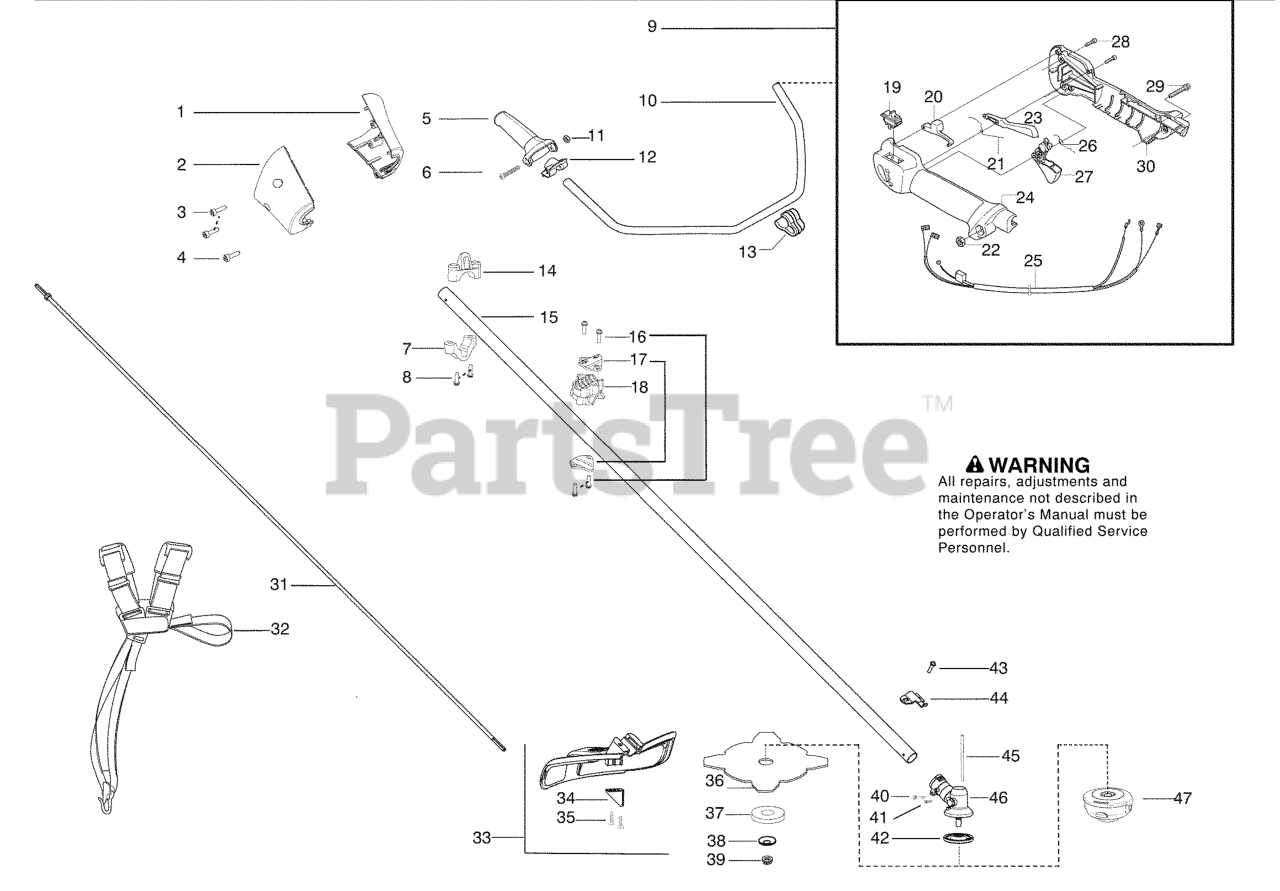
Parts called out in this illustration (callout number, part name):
1	NOSE CONE BH LEFT
2	NOSE CONE BH RIGHT
4	SCREW M4 X 1.75 PT 16MM
7	CLAMP HARNESS LOWER
9	ASSY THROTTLE HOUSING
14	CLAMP HARNESS UPPER
15	KIT-DRIVESHAFT(INCL. 40.41.44.
17	CLAMP BRACKET
19	STOP BUTTON
20	LOCKOUT STARTER THROTTLE
23	THROTTLE LOCK
25	ASSY CABLE WIRE HARNESS
27	THROTTLE TRIGGER
29	SCREW
31	Flexshaft
32	Harness w/warning
33	KIT COBI SHIELD
34	Limiter - Line
36	Blade - Grass
37	SUPPORTING CUP
38	SUPPORT FLANGE
39	GEARHEAD NUT - BRUSHCUTTER
40	SCREW - CARB. ADAPTOR
42	DRIVE DISC
43	SCREW 1/4-20 X 7/8 (TAP
44	BRACKET SHIELD STRAIGHT SHAFT
45	LOCKING PIN
46	ASSY GEARBOX
47	T25 10MM LH TRIMMER HEAD
